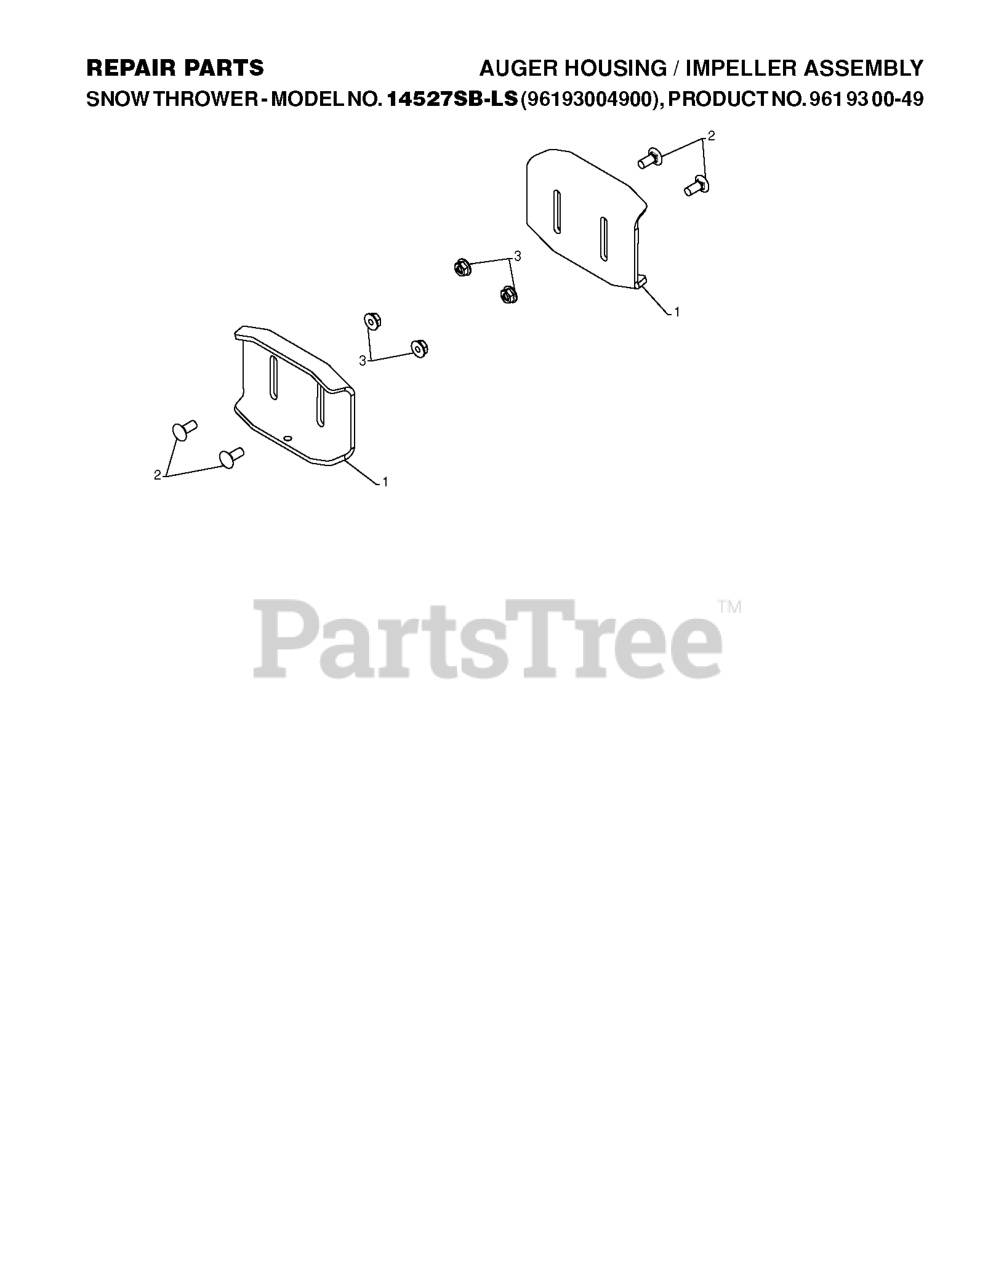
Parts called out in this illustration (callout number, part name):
1	SKID PLATE
2	BOLT
3	NUT.LOCK.5/16-18
